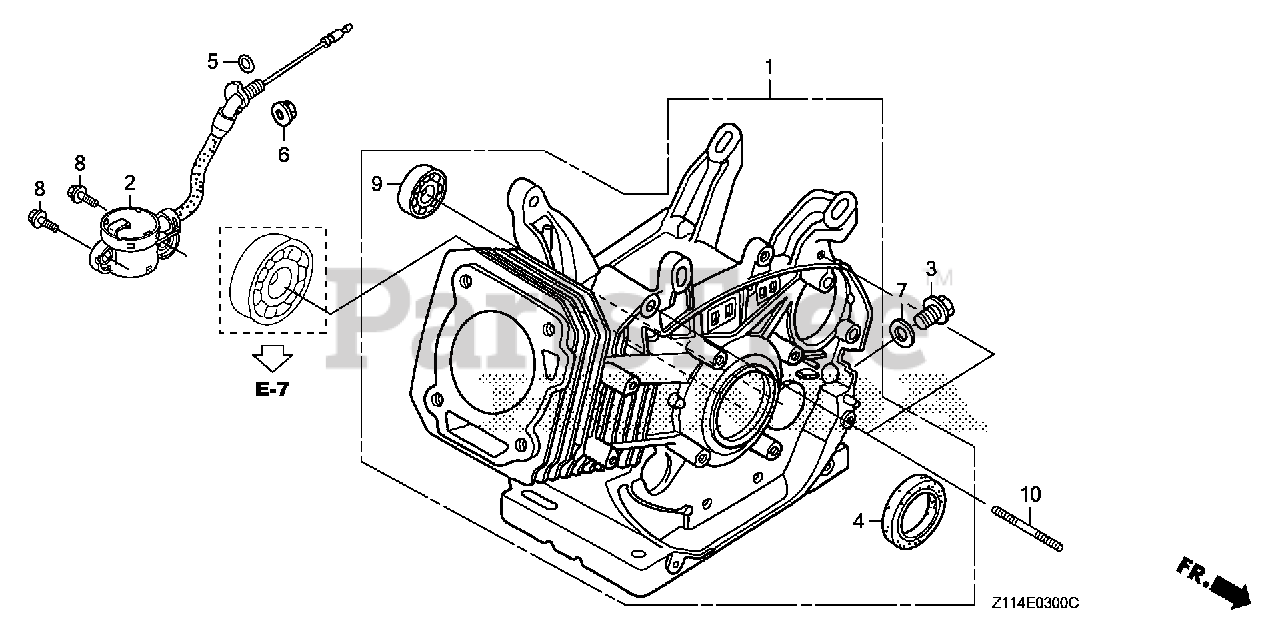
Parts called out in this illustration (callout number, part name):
1	CYLINDER ASSY.
2	SWITCH ASSY., OIL LEVEL
3	BOLT, DRAIN PLUG
4	OIL SEAL (35X52X8)
5	O-RING (14MM) (ARAI) Use up to Engine SN 2949254.
5	O-RING (14MM) (NOK)
6	NUT, FLANGE (10MM)
7	WASHER, DRAIN PLUG (12MM)
8	BOLT, FLANGE (6X12) Use up to Engine SN 1543277.
9	BEARING, RADIAL BALL (6202)
10	BOLT, STUD (6X30)
